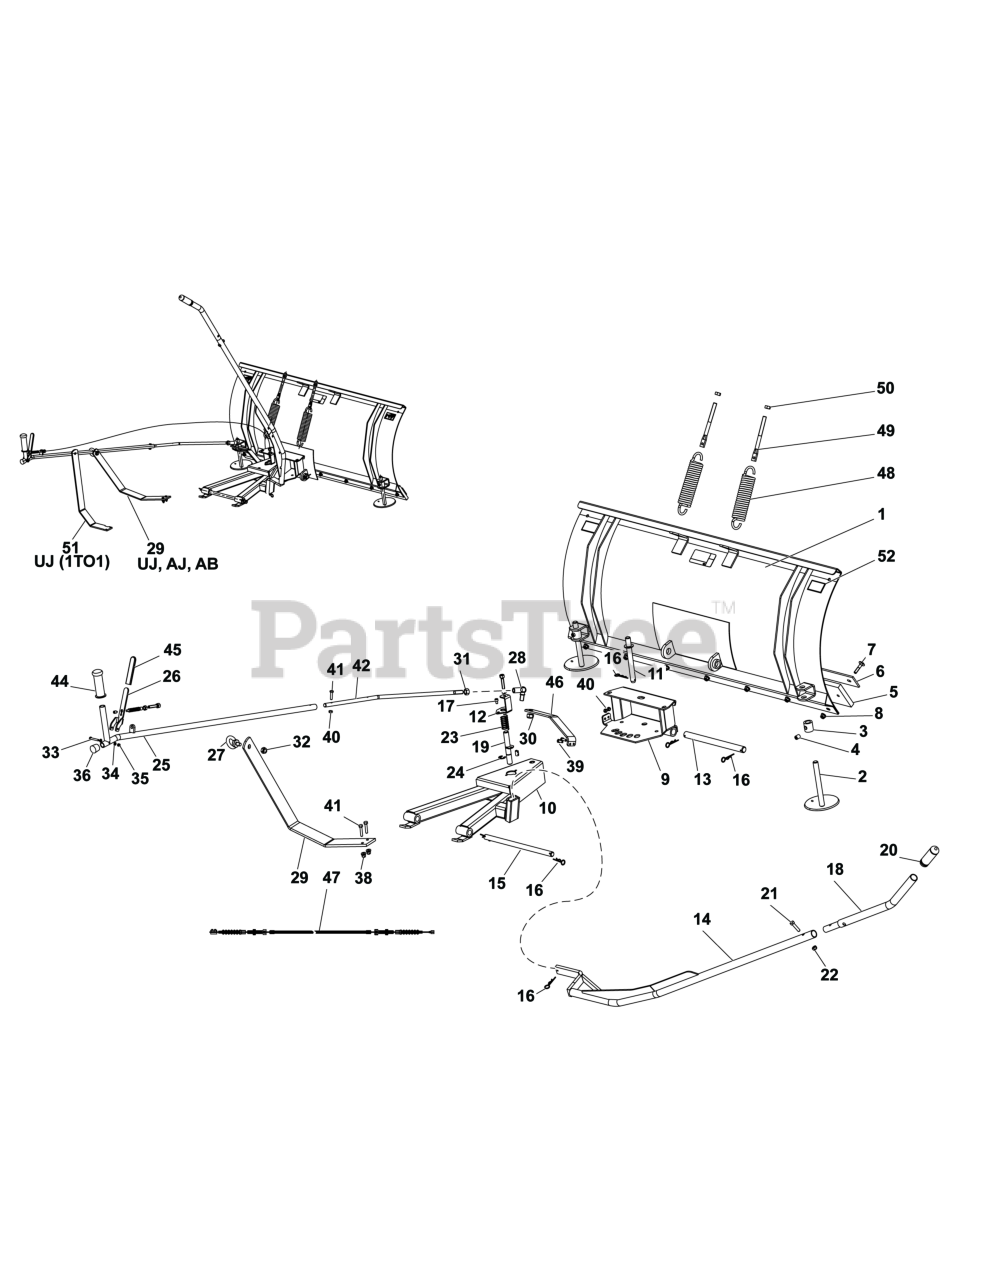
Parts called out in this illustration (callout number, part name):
1	BLADE, Dozer
9	HITCH ASSEMBLY
10	HITCH ASSEMBLY
18	LEVER, Control
28	JOINT, BALL
29	BRACKET
49	BAR
51	BRACKET
